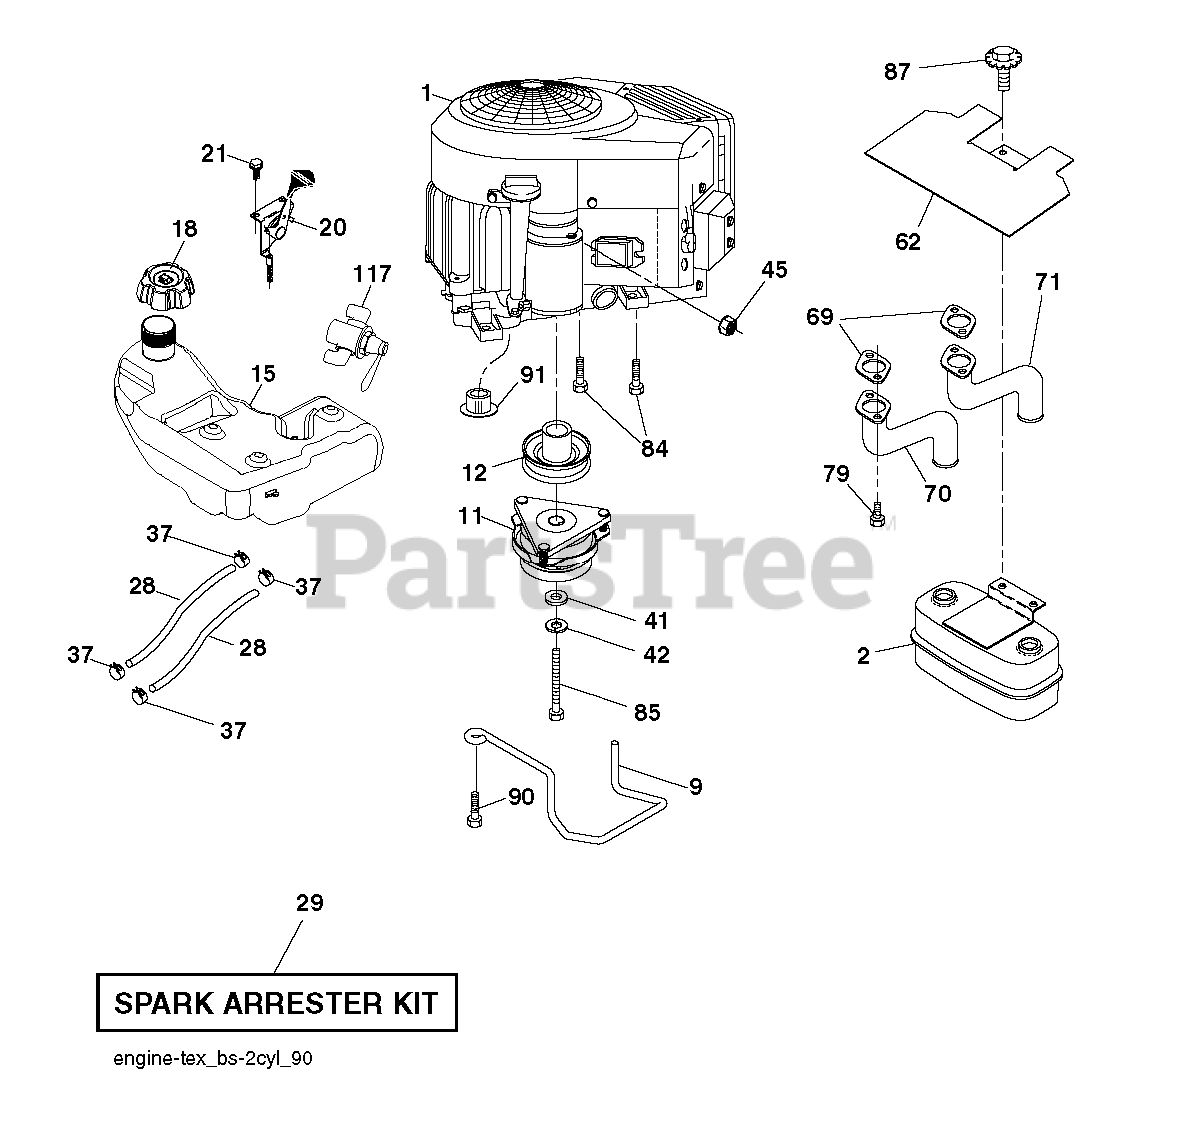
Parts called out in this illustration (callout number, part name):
2	MUFFLER.TWIN.CYL.LOW.TONE
9	KEEPER.BELT.ENGINE.4.2
11	CLUTCH.ELECTRIC.LT.48"*
12	PULLEY.ENGINE.TUFFTORQ
18	RP CAP FUEL
20	CONTROL.TH/CK.COBRA.B&S.TWN.BK
21	SCREW.#10 X 0.750.BOS
28	REPL BY 532 00 85-43
29	KIT.SPARK ARRESTOR 794945 B&S
37	HOSE CLAMP
42	LOCKWASHER
45	NUT
62	RP SHIELD HEAT MUFFLER
69	GASKET.MUFFLER
70	RP.EXHAUST.TUBE.LH.BS/TWIN
71	EXHAUST.TUBE.RH.BS/TWIN
79	SCREW.SOCKET.HEAD.5/16-18
84	SCREW.3/8-16
85	BOLT HEX 7/16-20X4-1/4"
87	BOLT 5/1618UNC X 3/4 W/ SEMS
90	SCREW 3/8-16X1
91	BUSHING.1.375OD
117	VALVE FUEL RESERVE
